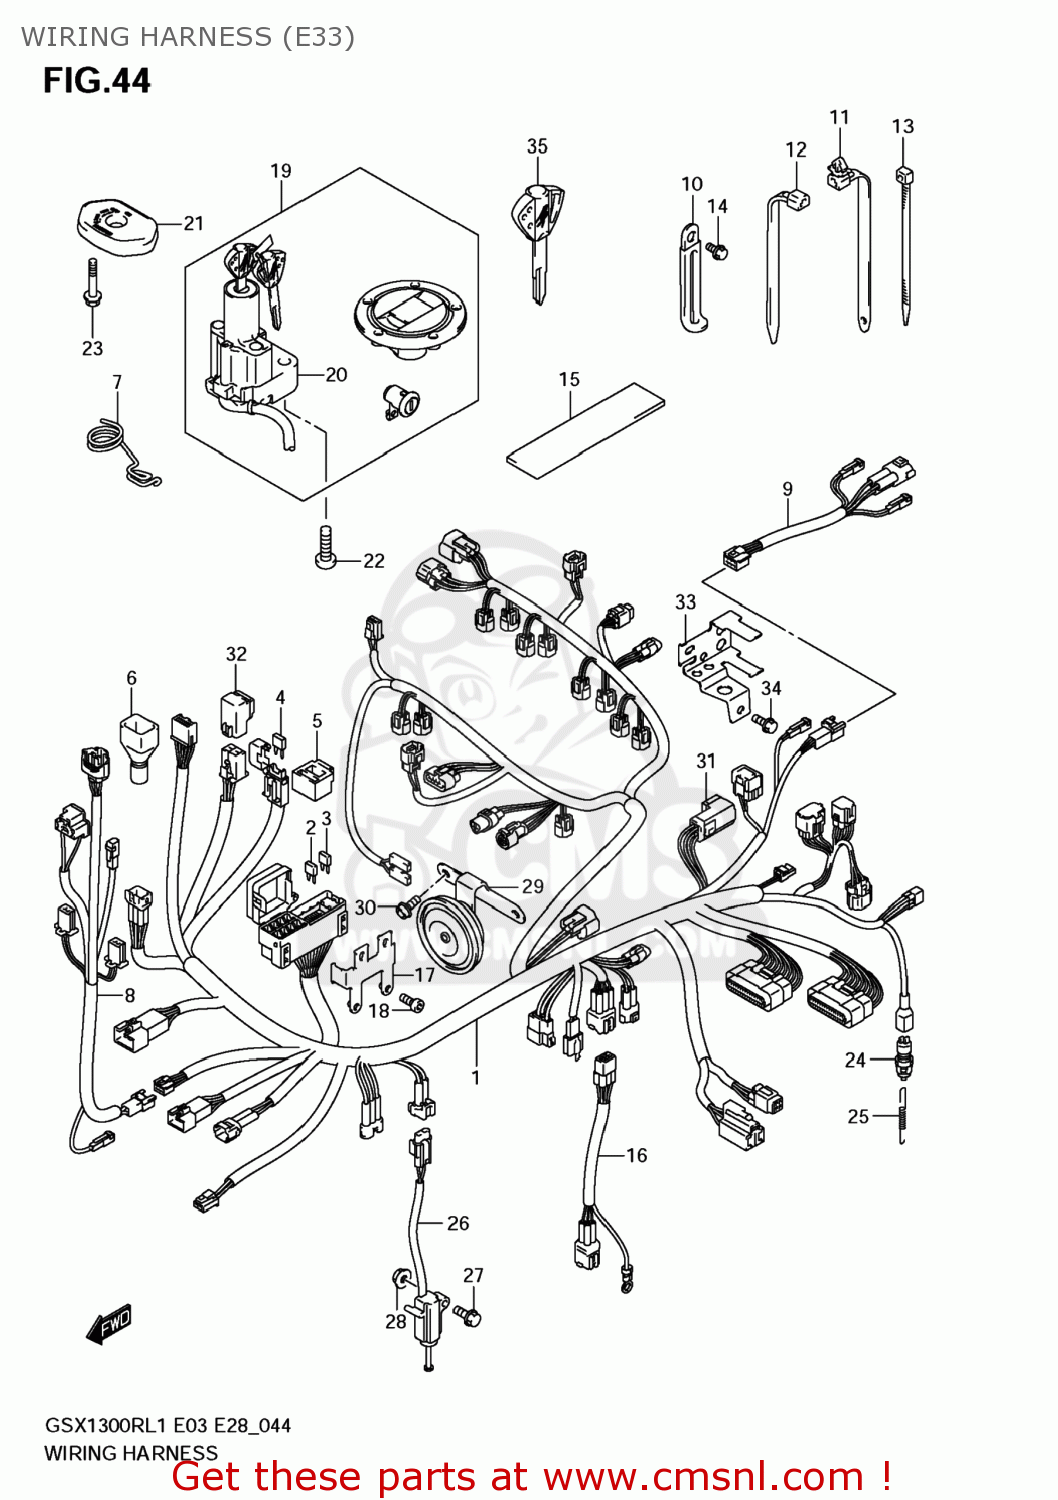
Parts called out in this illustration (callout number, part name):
1	HARNESS,WIRING
2	FUSE(10A)
3	FUSE(15A)
4	FUSE(15A)
5	HOLDER,FUSE
6	COVER,SPEEDOMETER COUPLER
7	GUIDE,WIRING HARNESS
8	HARNESS,WIRING NO.2
9	WIRE,RR COMB
10	CLAMP(L:45)
11	CLAMP(L:120)
12	CLAMP(L:125)
13	CLAMP(L:145)
14	BOLT
15	PROTECTOR,WIRING HARNESS
16	WIRE,O2 SENSOR
17	BRACKET,FUSE BOX
18	BOLT
19	LOCK SET
20	LOCK ASSY,STEERING
21	COVER,STEERING LOCK
22	BOLT(8X20)
23	BOLT
24	SWITCH ASSY,STOP LAMP
25	SPRING
26	SWITCH ASSY,SIDE STAND
27	BOLT(8X35)
28	NUT
29	HORN ASSY
30	BOLT
31	RELAY ASSY
32	RELAY ASSY
33	BRACKET,FUEL PUMP RLY
34	BOLT
35	KEY,BLANK
